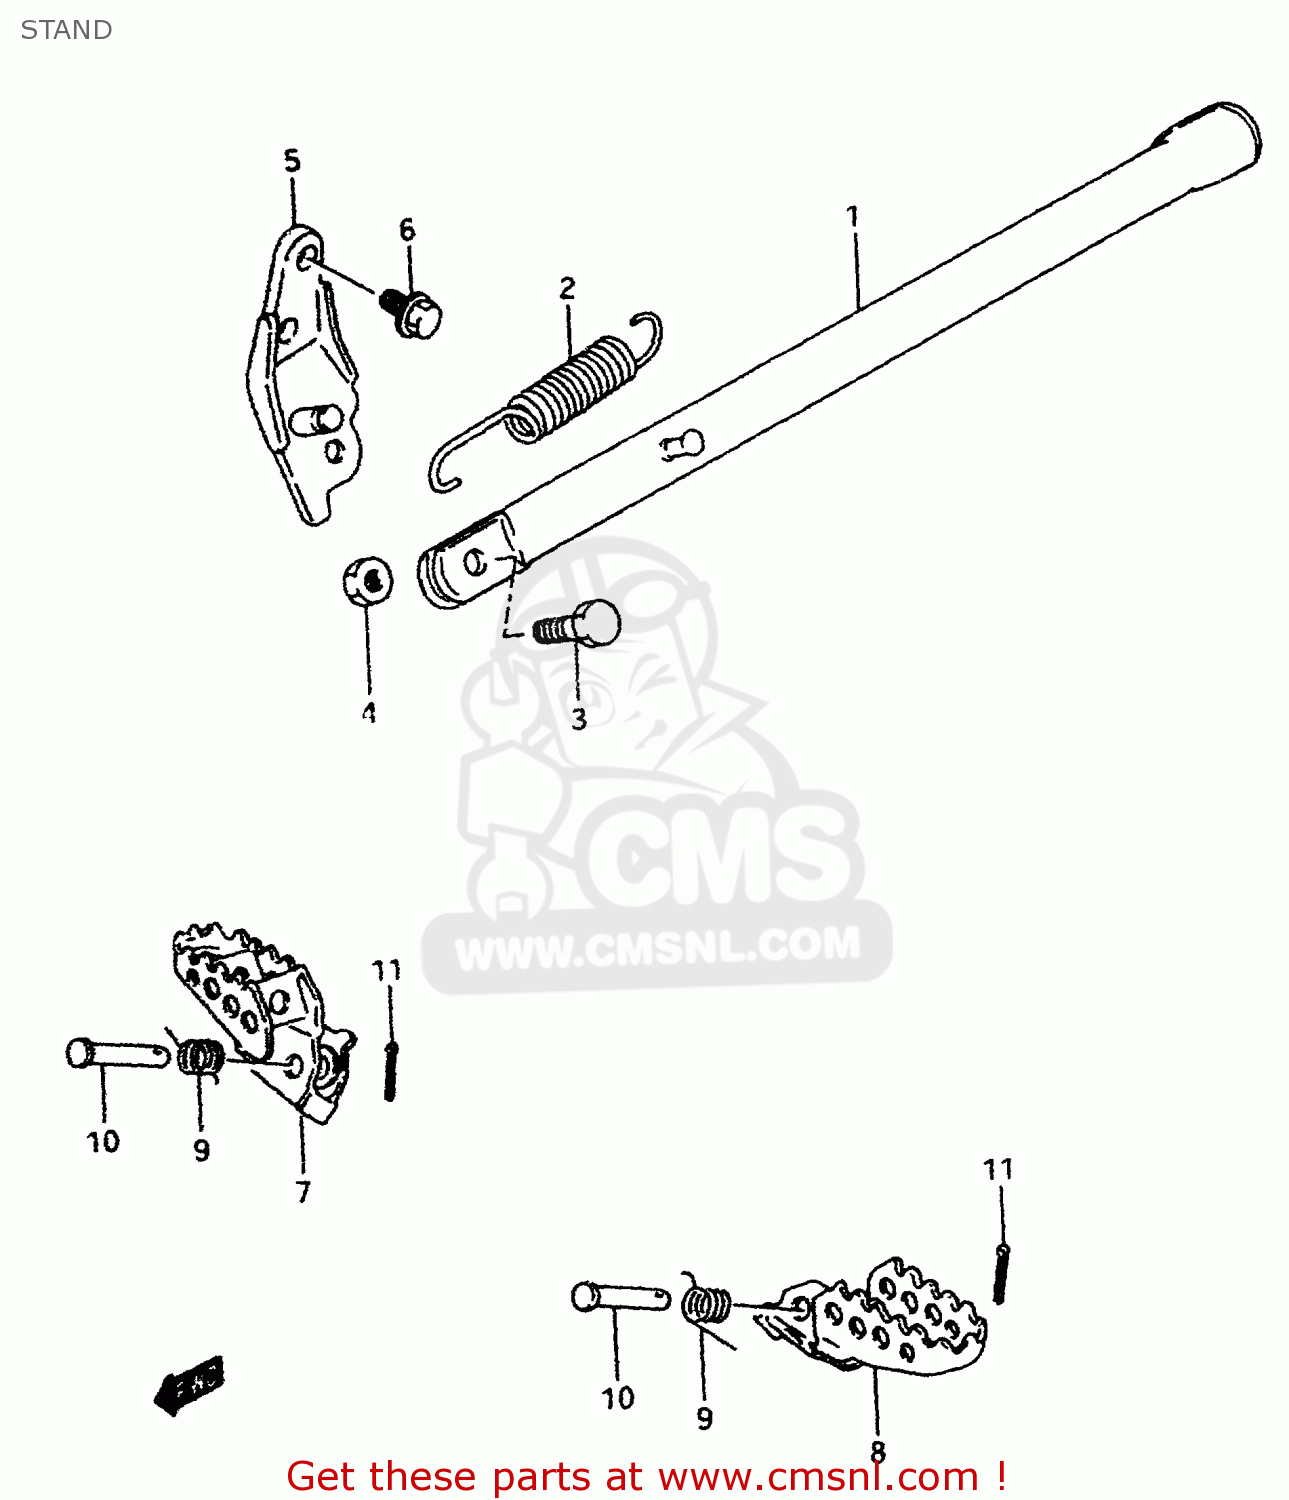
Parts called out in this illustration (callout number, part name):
1	STAND,PROP(BLACK)
2	SPRING
3	BOLT(8X25)
4	NUT
5	BRACKET,PROP STAND(BLACK)
6	BOLT
7	FOOTREST,FR,R
8	FOOTREST,FR,L
9	SPRING
10	PIN
11	PIN
